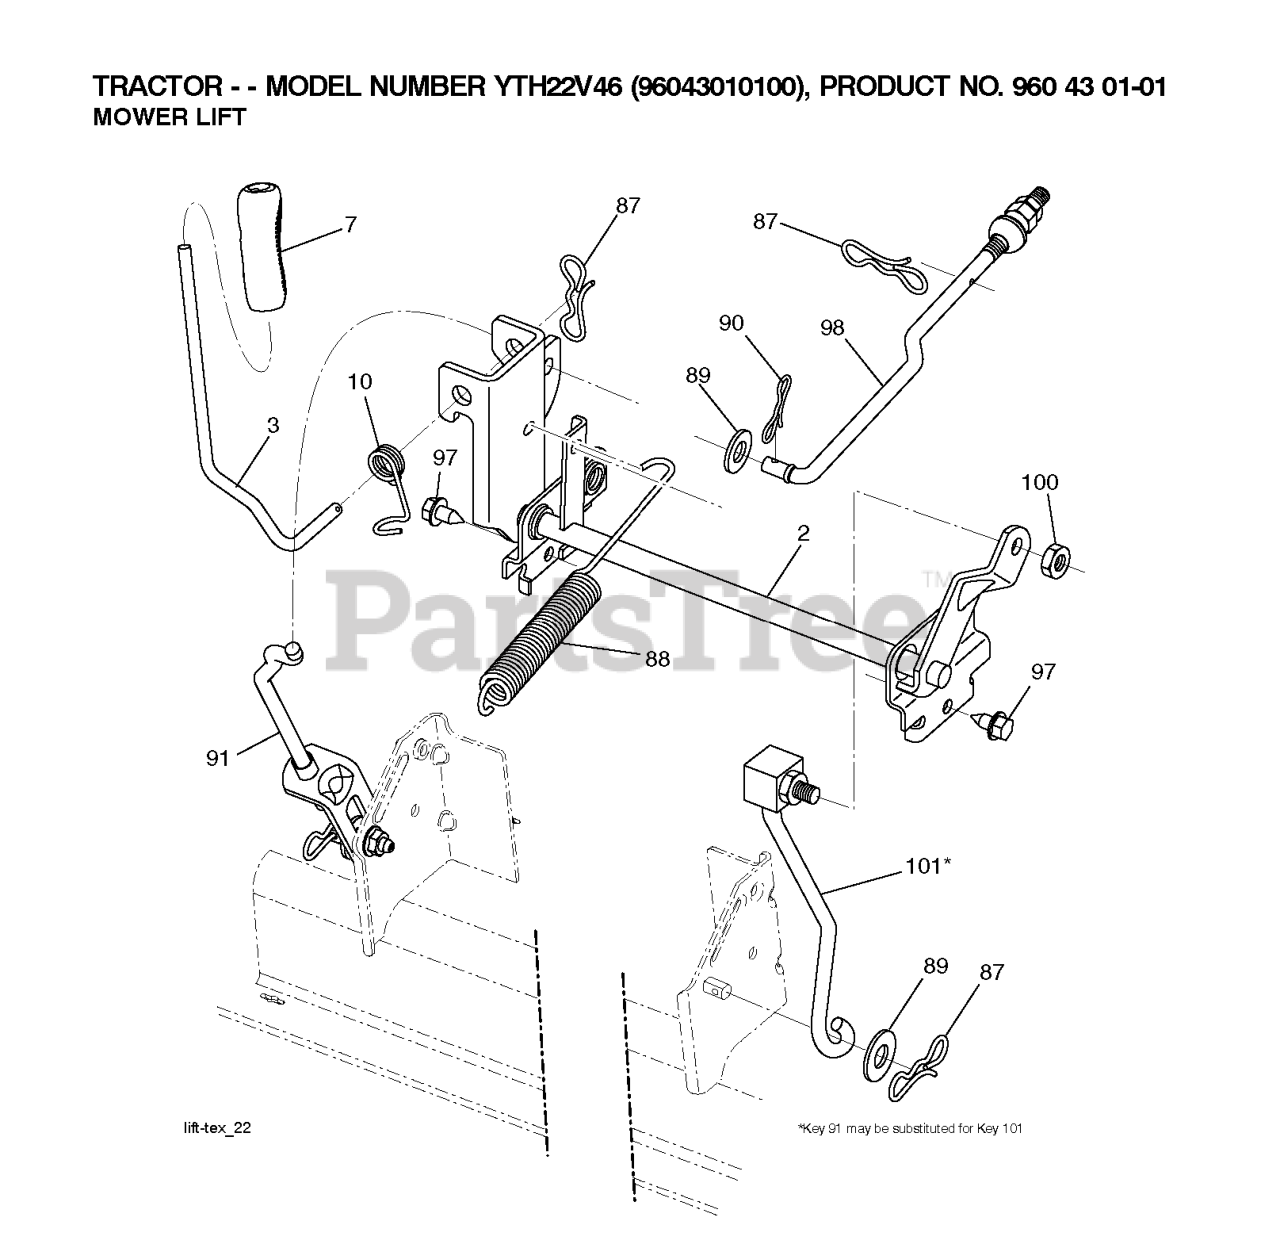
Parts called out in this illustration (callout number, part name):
2	SHAFT.ASM.CROSS.LIFT
3	LEVER.LIFT.HANDLE.LT
7	GRIP.HANDLE.LIFT.PVC.BLACK
10	SPRING.TORSION.LIFT.HANDLE
87	PIN.COTTER.7/16.BOW TI.
88	SPRING.LIFT.ASSIST
89	WASHER.CLEAR.ZINC
90	PIN.COTTER.5/16.BOW TI
91	LINK.ASM.LIFT.REAR
97	SCREW, 3/8-16X3/4
98	LINK.ASM.SUSP.FRONT.MW
100	LOCKNUT
101	LINK.ASM.LIFT.FIXE.38/42/46"
